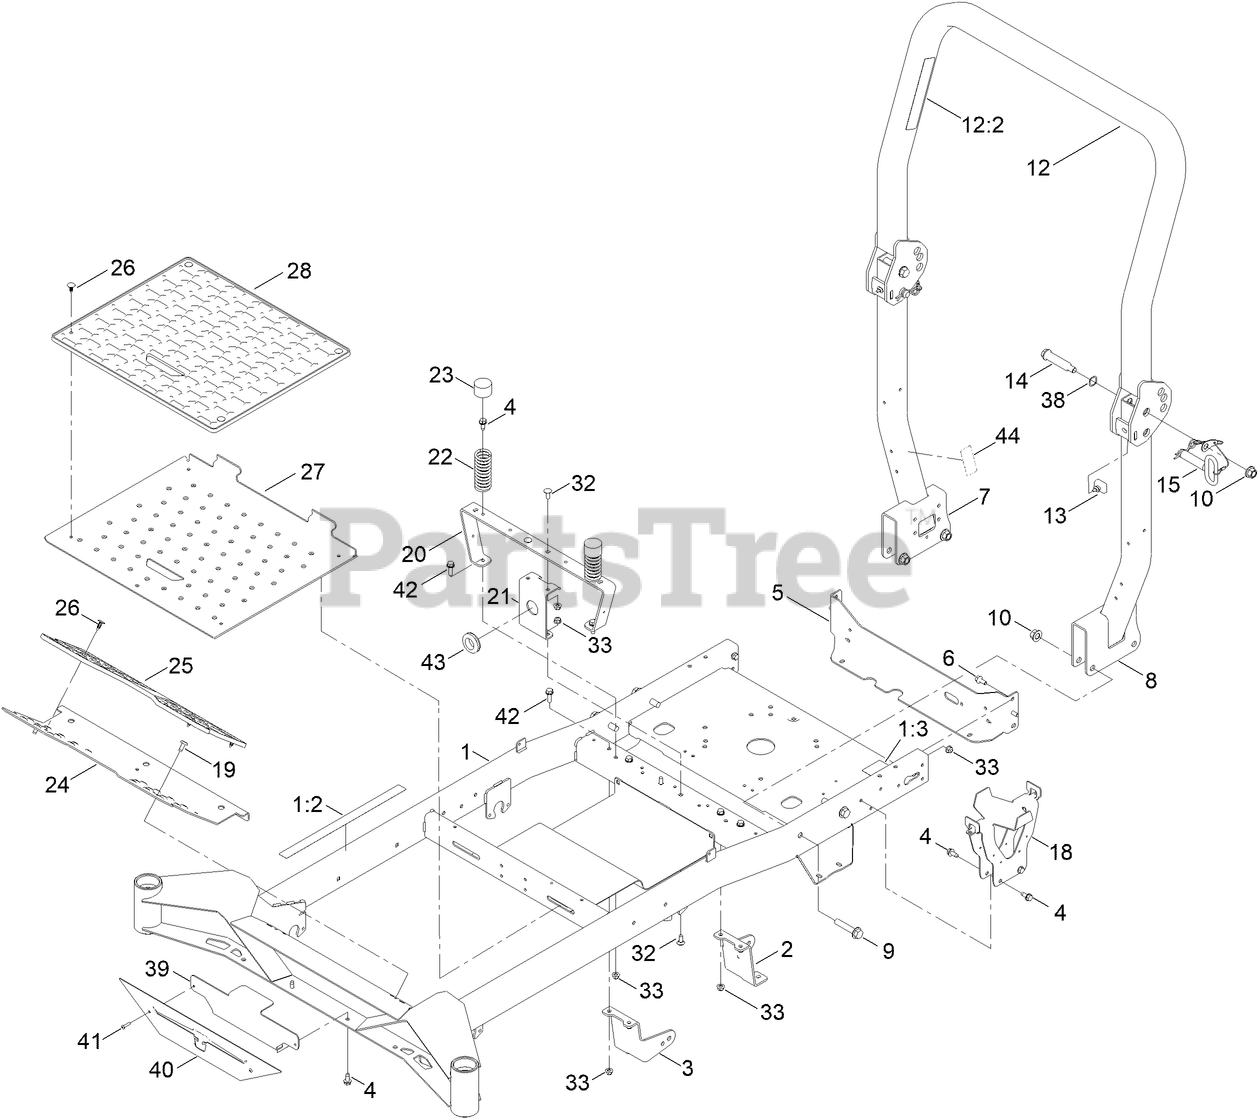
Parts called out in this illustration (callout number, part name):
1	FRAME W/DECALS ASM
1:2	DECAL-WARNING(AURORA)
1:3	DECAL-BYPASS
2	MOUNT-DRIVE, LH
3	MOUNT-DRIVE, RH
4	SCREW-HWHTF
5	PLATE-MOUNT, REAR
6	SCREW-HHF
7	RH ROPS ASM [BLACK]
8	LH ROPS ASM [BLACK]
9	SCREW-HHF
10	NUT-HF
12	TUBE-ROPS, UPPER ASM
12:2	DECAL-WARNING
13	BUMPER-ROPS
14	BOLT-SHOULDER
15	PIN-ROPS, ASM
18	TRAY-BATTERY
20	SUPPORT-SEAT
21	BRACKET-LATCH, FRAME (MTY/BTV)
22	SPRING-COMPRESSION
23	CAP-PROTECTOR
24	PAN-FLOOR
25	FLOOR MAT - TITAN
26	PLUG-PLASTIC
27	PAN-FLOOR
28	FLOOR MAT
32	SCREW-CARR
33	NUT-HF, NI
38	WASHER-WAVE
39	PLATE-BACKER
40	LOGO-PLATE-FRONT
41	RIVET-TRIFOLD
42	SCREW-HHF
43	GROMMET
44	DECAL-COMPLIANCE, ROPS
